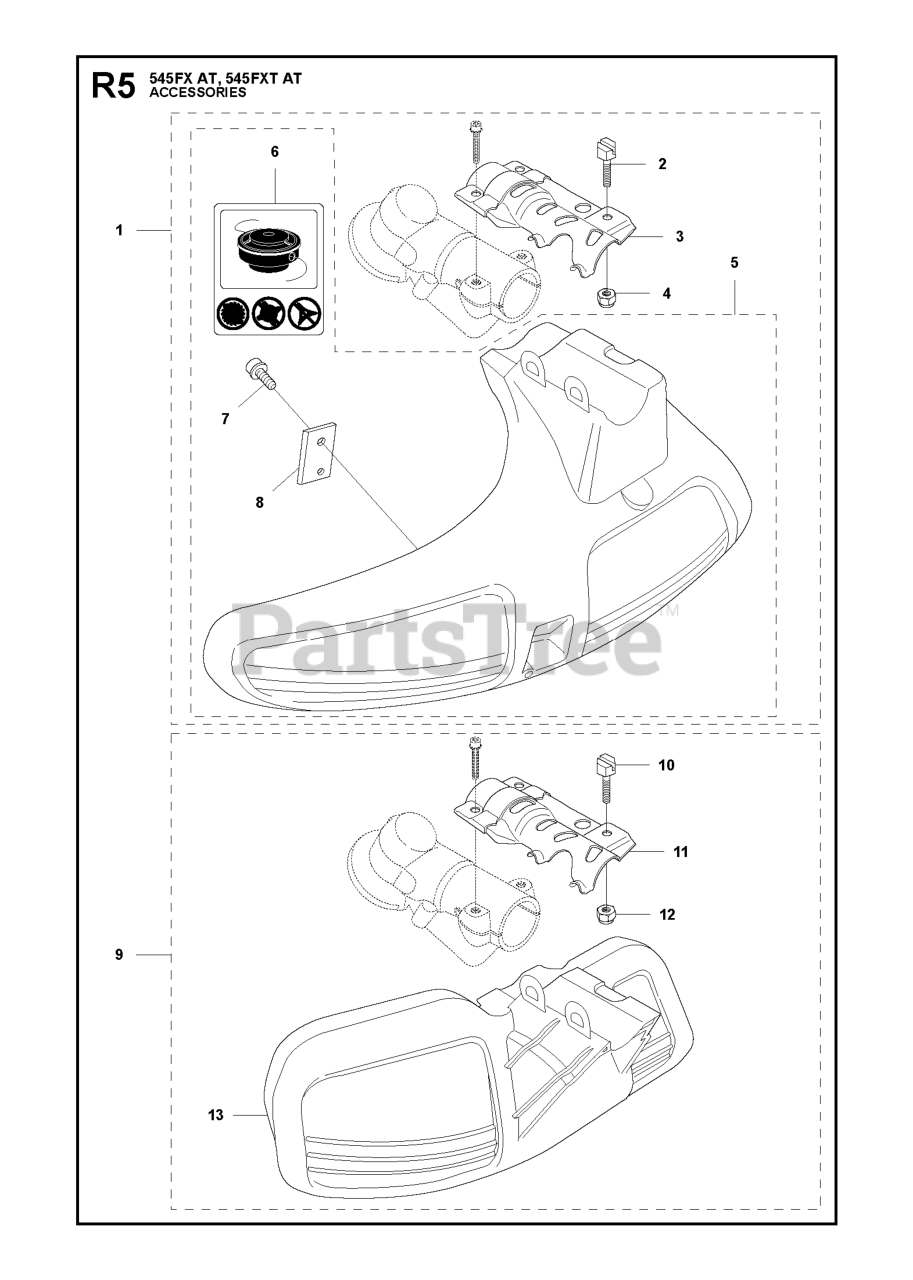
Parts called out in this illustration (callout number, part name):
1	TRIMMER GUARD ASSY
4	LOCKNUT M6
9	TRIMMER GUARD COMPL
12	LOCKNUT M6
13	BLADE GUARD
